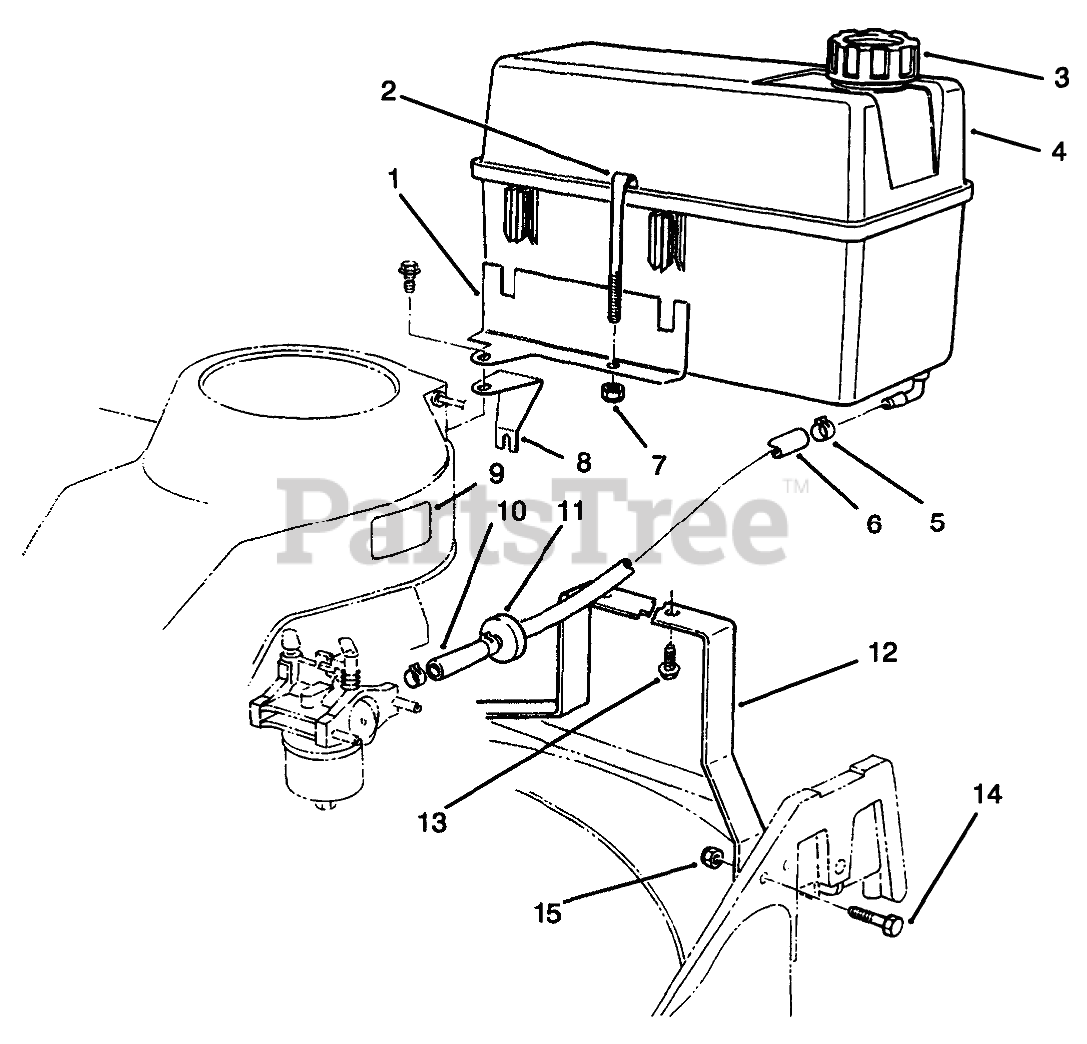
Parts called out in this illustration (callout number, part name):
1	Bracket Tank
2	RETAINER - FUEL TANK
3	GAS CAP ASM
4	Tank-Gas
5	CLAMP-FUEL LINE
6	HOSE-FUEL
7	NUT-LOCK, NI
8	Support-Bracket
9	DECAL - FUEL
10	LINE-GAS
11	FILTER-FUEL
12	Base-Tank, Fuel
13	SCREW-HWH
14	SCREW-HH
15	NUT-LOCK, NI
